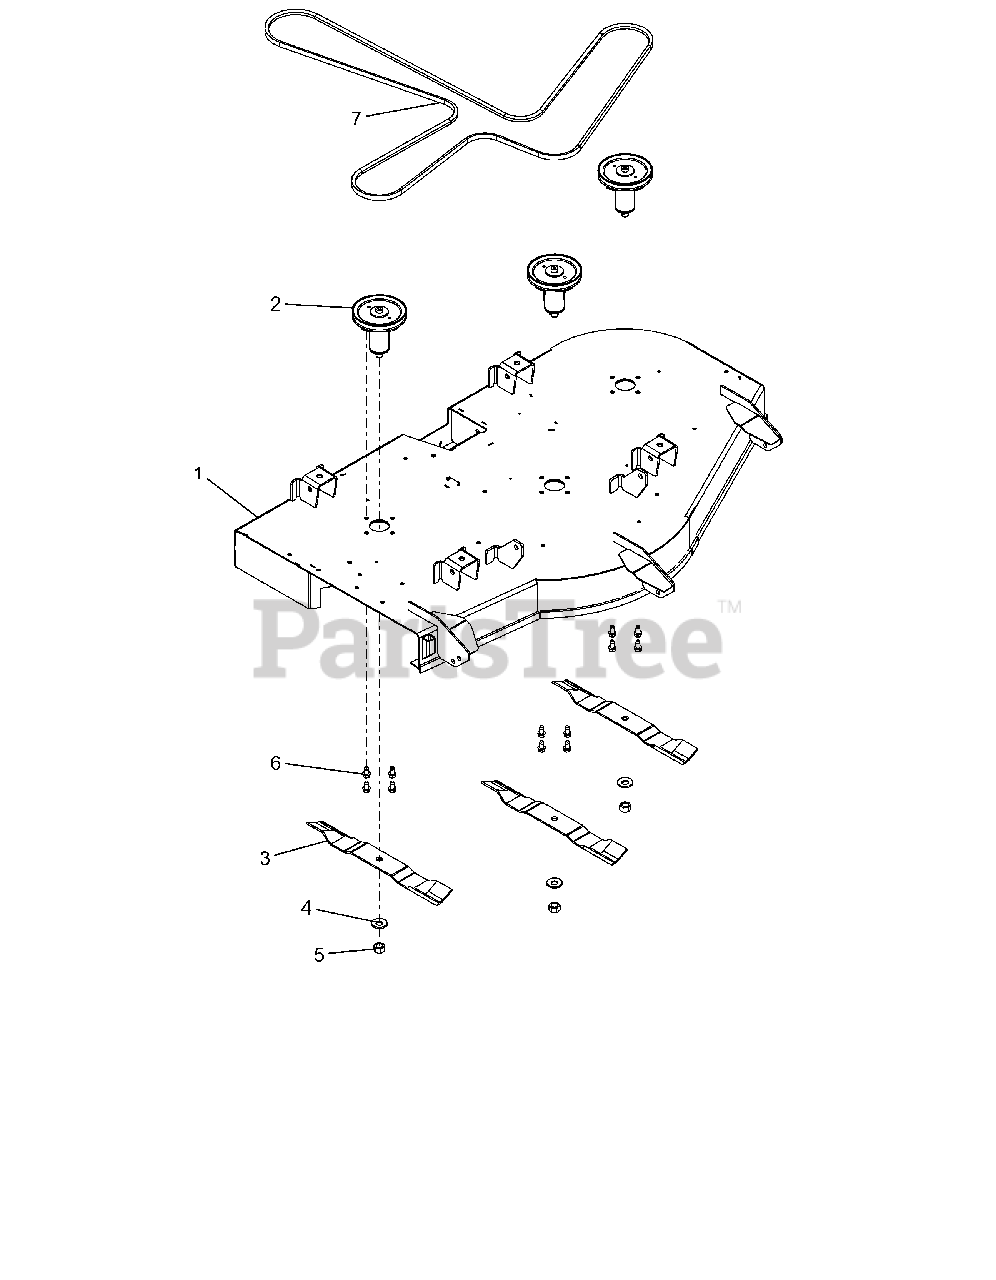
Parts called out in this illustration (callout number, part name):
1	KIT, 52" GRAVELY DECK W/DECALS
2	KIT, DECK SPINDLE ASM-52
3	BLADE, 18" - 30 DEG .5 OFFSET
4	WSHR-BLVL .669X1.535X.138
5	NUT-STD .625-18 ZCC
6	SCR,TAP .375-16X.75 HWH TR ZCC
7	V-BELT, HA-WRAPPED
